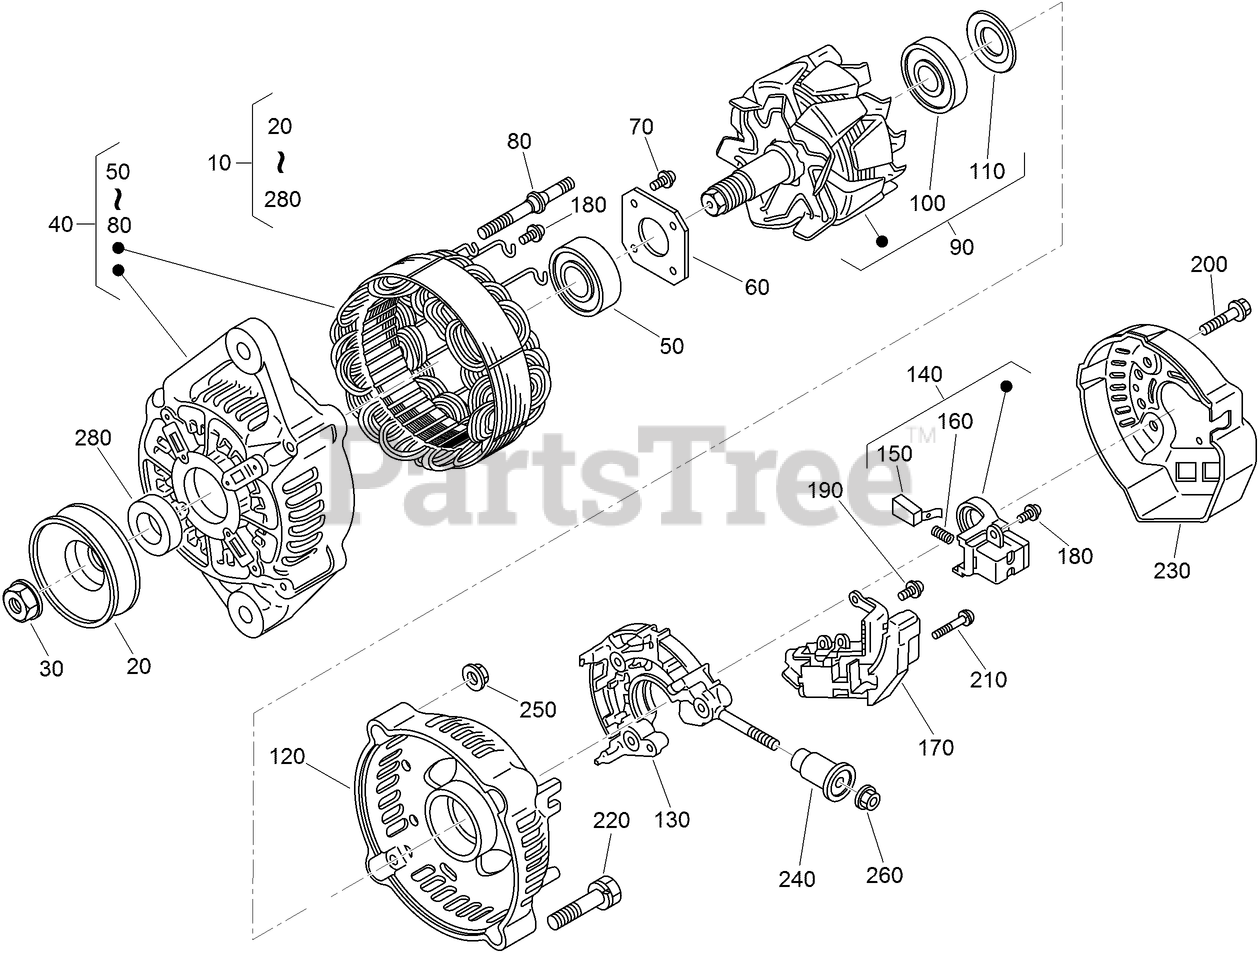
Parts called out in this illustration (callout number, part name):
10	60 AMP ALTERNATOR ASM
20	PULLEY-DYNAMO
40	DRIVE END FRAME ASM
60	PLATE-RETAINER
70	SCREW-HEAD, ROUND
80	BOLT-THROUGH
90	ROTOR ASM
100	COVER-BEARING
110	BEARING-BALL
120	FRAME-END
130	HOLDER
140	BRUSH HOLDER ASM
150	BRUSH
160	SPRING-BRUSH
170	REGULATOR ASM
180	SCREW-HEAD, ROUND
190	SCREW-HEAD, ROUND
210	SCREW-HEAD, ROUND
230	COVER-END
240	INSULATION-BRUSH
280	COLLAR
